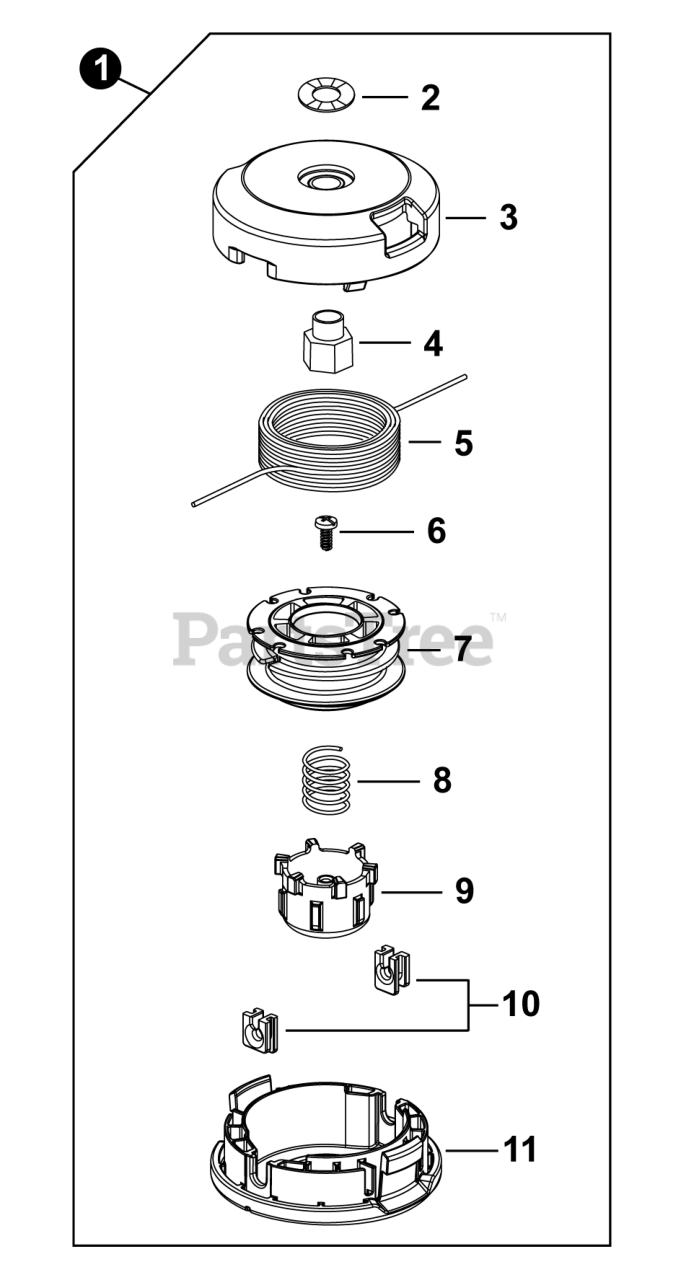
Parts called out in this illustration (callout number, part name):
1	TRIMMER HEAD
2	WASHER 24
3	COVER, SPOOL
4	BUSHING
5	LINE, NYLON TRIMMER
11	HOUSING, SPOOL
